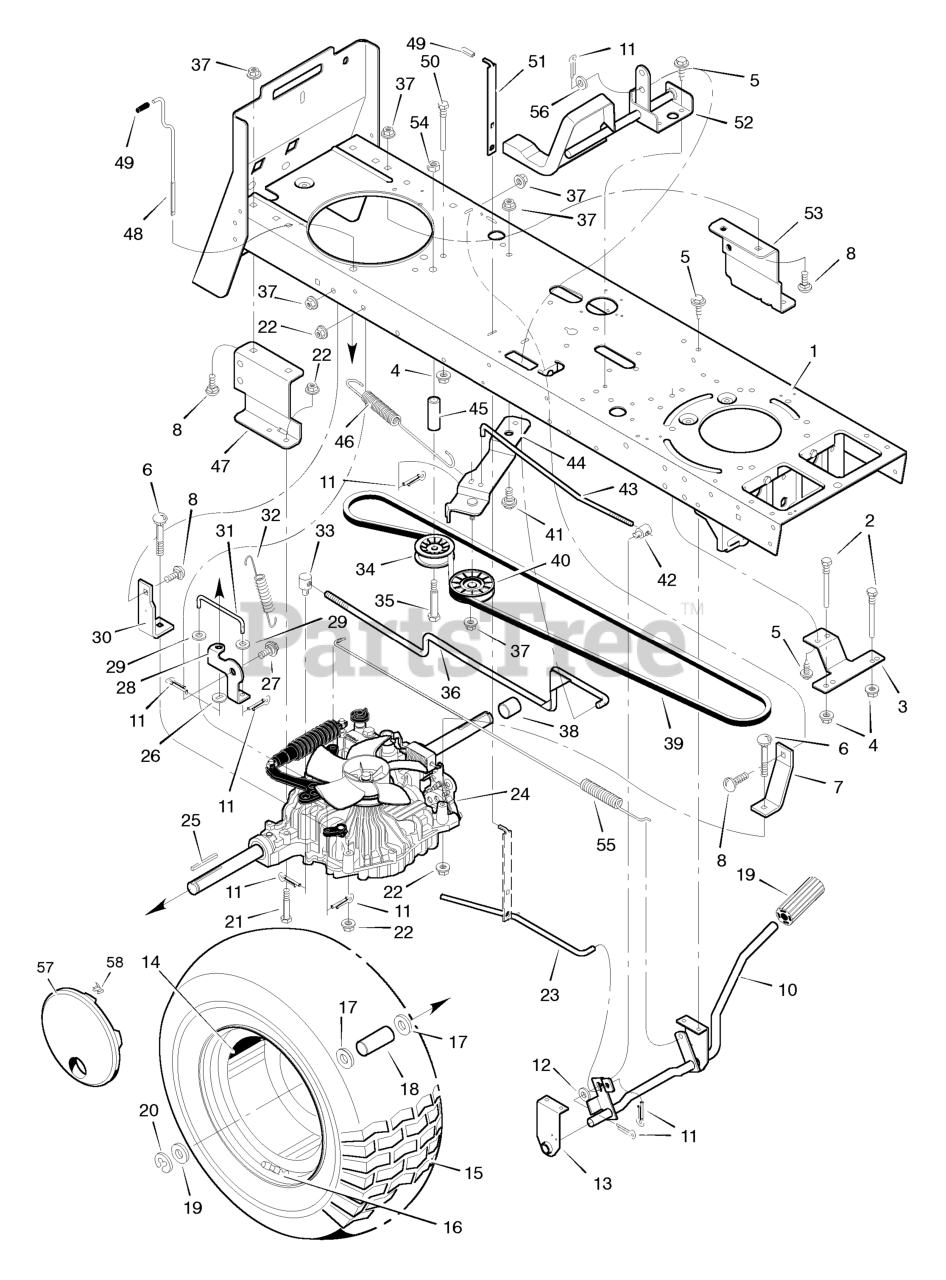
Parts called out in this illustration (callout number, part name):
1	Frame Assembly
2	Guide, Belt
3	Bracket, Belt Guide
4	Nut, Flange
6	Bolt, Carriage
7	Bracket, Torque
8	Bolt, Carriage
9	Pedal
10	Lever Assembly, Pedal
11	Pin, Cotter
12	Washer
13	Support, Pedal
14	Wheel and Tire Assembly
15	Tire *
16	Valve Stem
17	Washer
18	Spacer
19	WASHER, 1-1.3 16G FLT
20	E- Ring
21	Bolt, Hex
22	Nut
23	Rod, Latch
24	Transaxle
25	Key, Square
27	Bolt, Shoulder
28	Bracket, Dump Valve
29	Washer
30	Bracket, Torque
31	Rod, Dump Valve
32	Spring, Extension
33	NUT, Adjusting, 1/2-13
34	Pulley, Idler
35	Bolt, Hex
36	Rod, Control
37	Nut
38	Spacer
40	Pulley, Idler
41	Bolt, Shoulder
42	Nut, Adjusting
43	Rod, Clutch
44	Bracket, Idler
45	Spacer
46	Spring, Extension
47	Bracket, Right Transaxle
48	Rod, Dump Valve
50	Guide, Belt
51	Lever, Parking Brake
52	Pedal Assembly
53	Bracket, Left Transaxle
57	Disc, Wheel
58	Clip, Retainer
